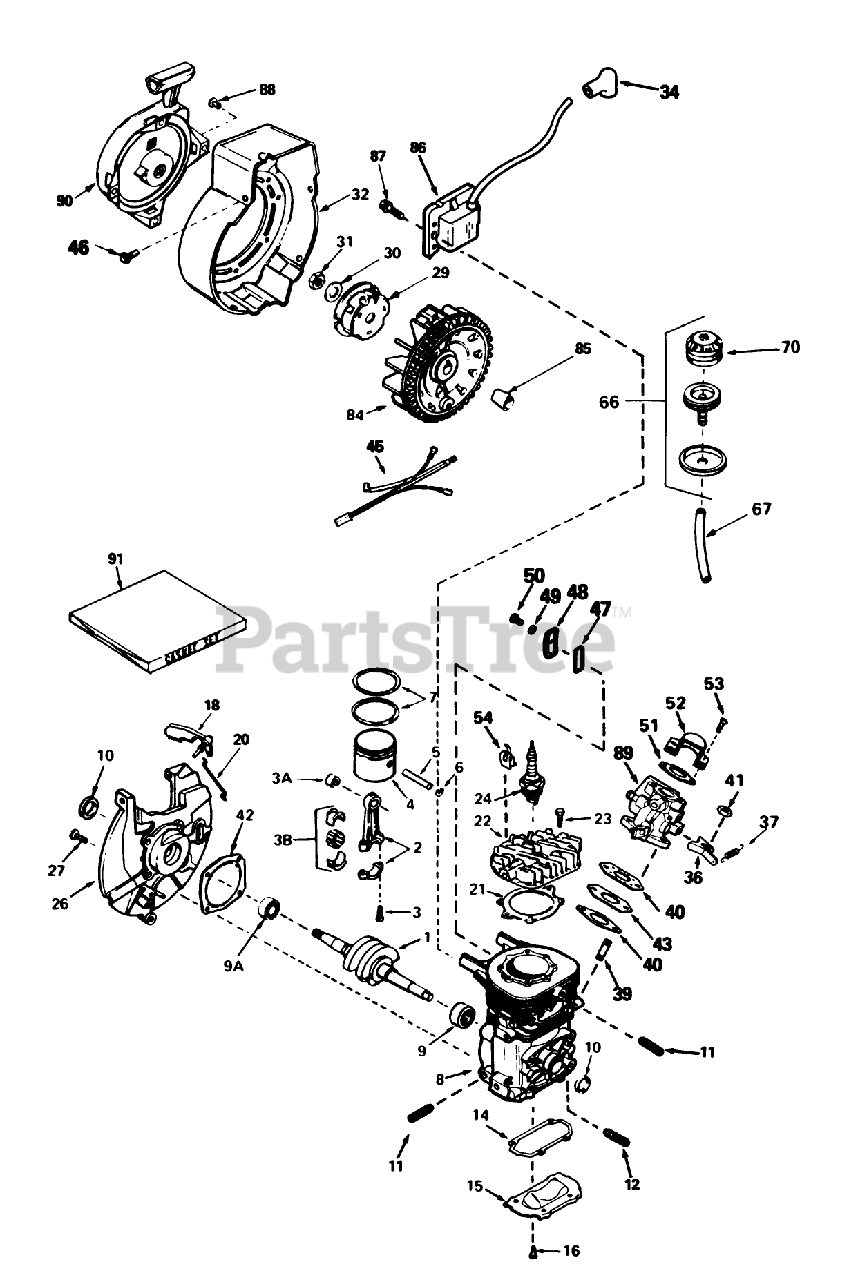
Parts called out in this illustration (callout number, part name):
1	Crankshaft
2	Rod Assy., Connecting (Incl. Ref. #2, 3 4)
3	Bolt-Rod, Connecting
3A	Bearing-Cartridge
3B	Bearing Liner Set-Needle
4	Piston
5	Pin-Piston
6	Ring-Retaning
7	Ring Set
8	Block Assy.-Cylinder (Order short block if replacement is required.)
9	Bearing-Cartridge
9A	Bearing-Ball
10	Seal-Oil
14	Cover
15	Plate-Cover
16	Screw (T-25, 10-24 x 1/2)
18	Vane-Air
20	Link-Governor
21	Gasket, Head
22	Head-Cylinder
23	Screw (T-30, 1/4-20 x 3/4)
24	Spark Plug-Resistor (R C J 8Y)
26	Base Assy.-Blower Housing (Incl. Ref. #10)
27	Screw (1/4-20x19/32)
29	Cup-Starter
30	Washer-Spring
31	Nut-Flywheel
32	Housing-Blower
34	Cover-Spark Plug
36	Lever-Adjusting, Rpm
37	Spring-Governor
40	Gasket-Carburetor
41	Locknut
42	Gasket, Shroud Base
43	Spacer
45	Harness-Wire
46	Screw-Hex, Hd.
47	Gasket-Cover
48	Comp. Release Cover
49	Washer
50	Screw (T-25, 10-24 x 1/2)
51	Gasket
52	Baffle-Carburetor
53	Screw
66	Primer Assy.
67	Line-Primer
70	Bulb-Primer
84	FIywheel
85	Blade (20 inch)
86	Solid State
87	Screw
88	Rivet-Pop (3/16" dia) (Can be purchased locally)
89	Carburetor (Incl. Ref. #40)
90	Starter-Rewind
91	Gasket Set
